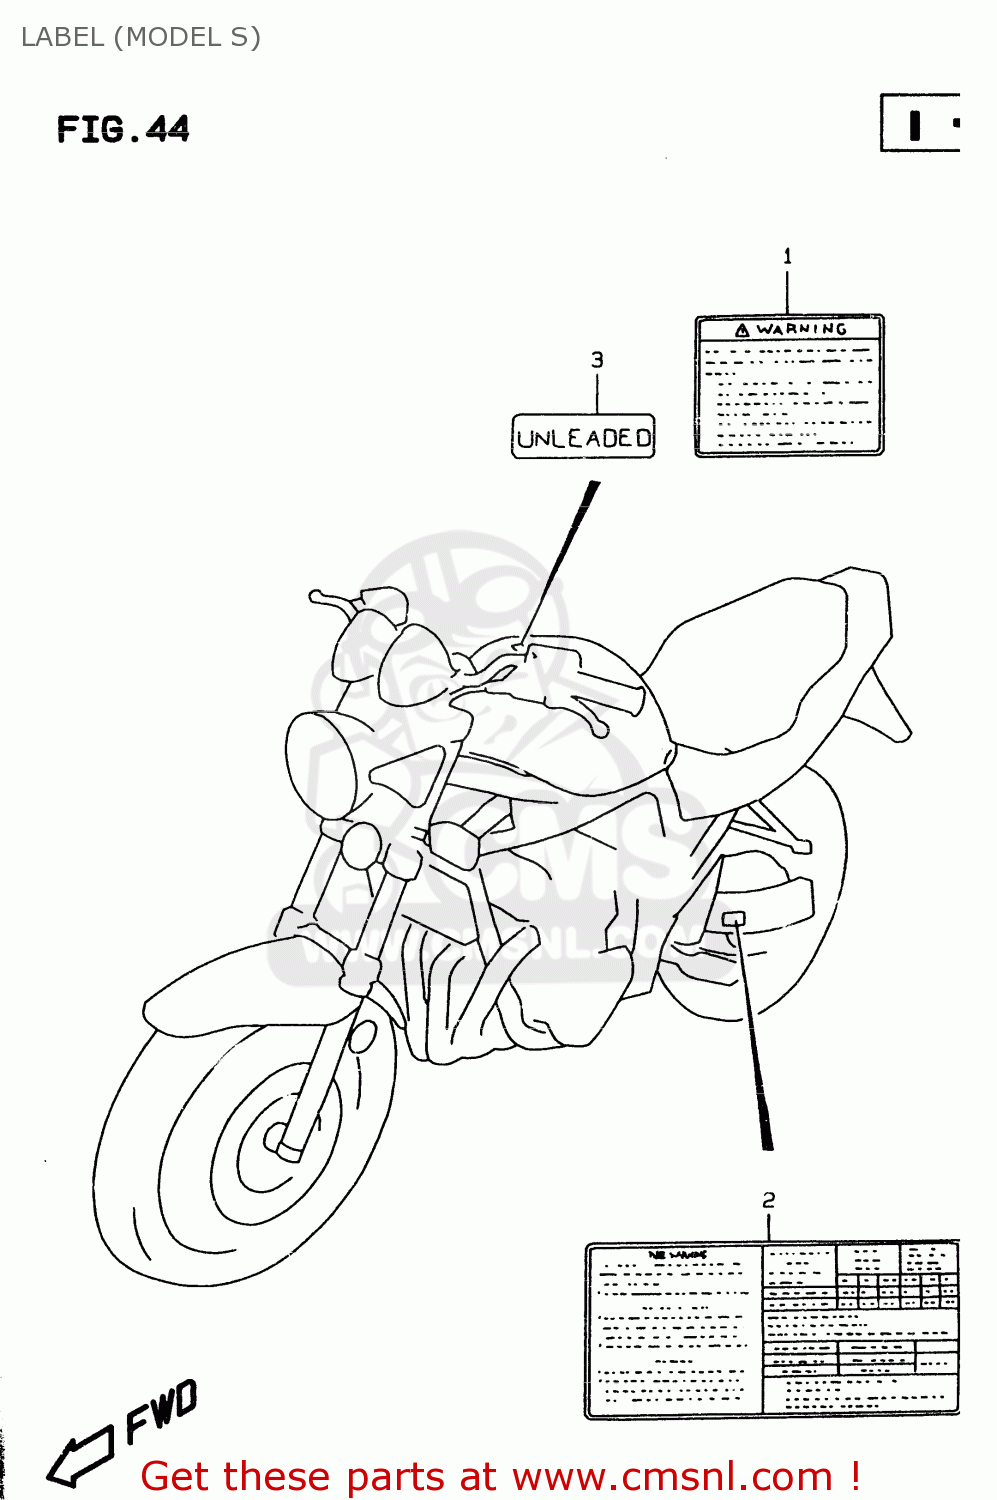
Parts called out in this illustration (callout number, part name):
1	LABEL, WARNING SAFETY
2	LABEL,TIRE AIR
3	LABEL,CAUTION
